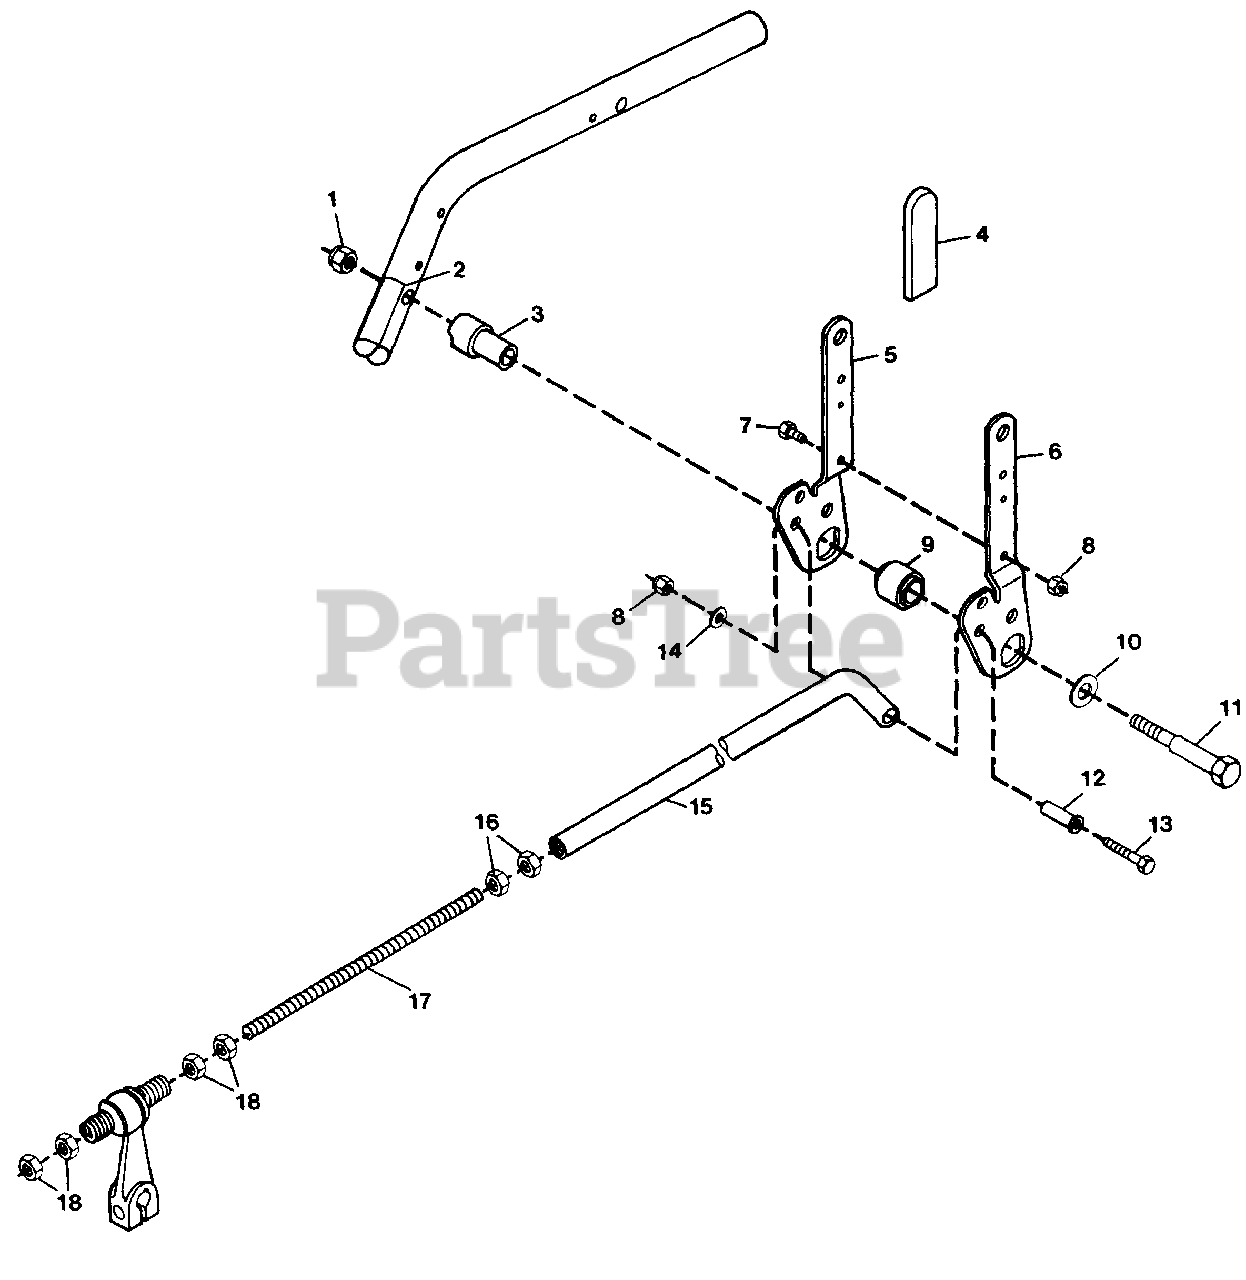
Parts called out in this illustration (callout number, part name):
1	NUT, LOCK 1/2-13 E.T.
2	DECAL, GEAR SHIFT
3	PIVOT, HAND LEVER L.H.
4	GRIP, HANDLE
5	HANDLE, CONTROL R.H.
6	HANDLE, CONTROL L.H.
7	BOLT, HEX 1/4-20X.625
8	NUT, LOCK 1/4-20
9	BUSHING, HANDLE
10	WASHER, FLAT .531X1.062X.095
11	BOLT, HEX STEP
12	BUSHING, OPER. PRESENCE HANDLE
13	BOLT, HEX 1/4-20X1.50
14	WASHER, FLAT .281X.625X.065
15	ROD, CONTROL HI-LO
16	NUT, HEX 3/8-16
17	ROD, CONTROL EXTENSION
18	NUT, JAM 3/8-16 HEX
